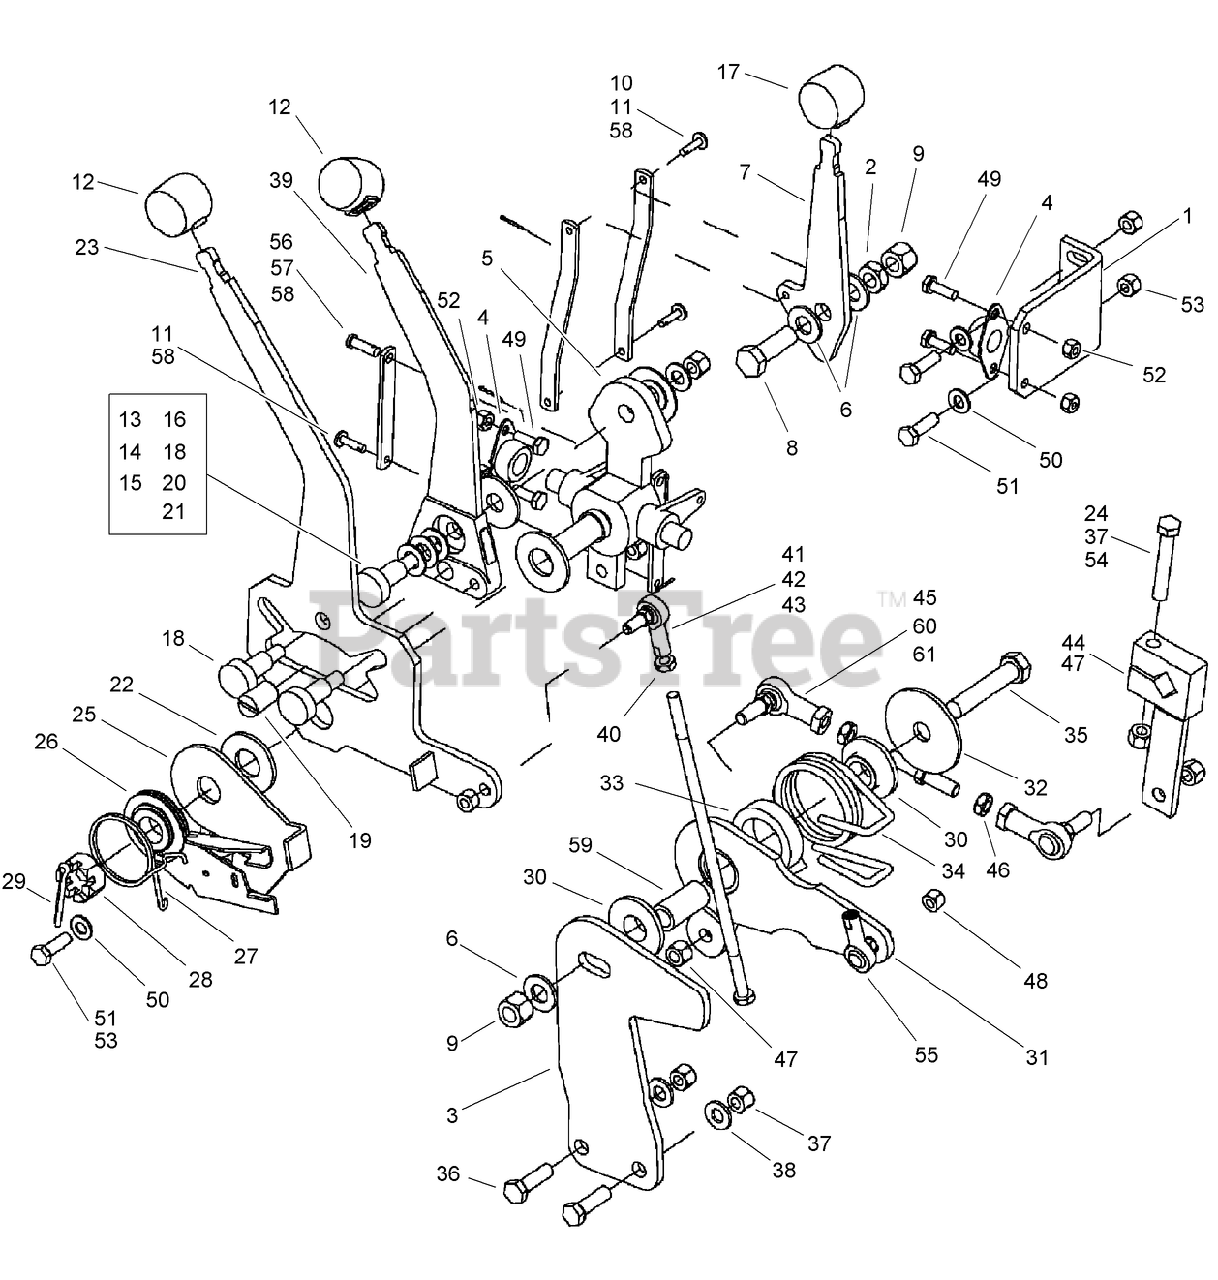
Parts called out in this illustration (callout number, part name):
1	ANGLE - Mounting
2	NUT-JAM
3	PLATE-CENTERING
4	BEARING
5	PIVOT-CONTROL, STEERING
6	WASHER-0.531 x 1.062 x 0.092 in CST ZND
7	HANDLE - Plow
8	SCREW-HH
9	NUT-LOCK, HEX
10	LINK - Control Valve
11	PIN-CLEVIS
13	WASHER-FRICTION
14	WASHER-BELLEVILLE
15	WASHER-0.406 x 0.812 x 0.065 in CST ZND
16	NUT
17	KNOB-GREEN
18	BOLT - Shoulder
19	BALL-PLUNGER
20	RACE-THRUST
21	BEARING-THRUST (NEEDLE)
22	WASHER-SPACER
23	PLATE - Handle
24	LEVER - Pump Control
25	PLATE - Center
26	NEUTRAL SWITCH MOUNTING ASM
27	SPRING-CENTERING
28	NUT-SLOTTED, HEX
29	PIN - Cotter .188 x 1.50 in ZND
30	BUSHING-INSERT, PLASTIC
31	PIVOT - Centering
32	WASHER-FLAT (SPECIAL)
33	SPACER-COLLAR
35	SCREW-HH
36	BOLT
37	NUT-HEX
38	WASHER-FLAT
39	HANDLE - Creep
40	NUT-JAM
41	JOINT-BALL (FEMALE)
42	ROD-ADUST
43	ROD END - Female Ball Joint LH
44	NUT-JAM, HEX
45	NUT-JAM, LH
46	SCREW-JACK, CONTROL
47	NUT-HEX
48	NUT - Prev Trq 5/16 GRC CAD Direct
50	WASHER-FLAT
51	SCREW-HH
52	NUT-Prev Trq 1/4 GRC PHC Direct
53	NUT-HEX
54	BOLT - Hex Hd .375 x 2.25 GR5 ZND
55	JOINT-BALL, LH (FEMALE)
56	LINK - Strg Valve
57	PIN
58	PIN - Cotter .062 x .50 in ZND
60	JOINT-BALL, STUD (ROD END)
61	JOINT-BALL
